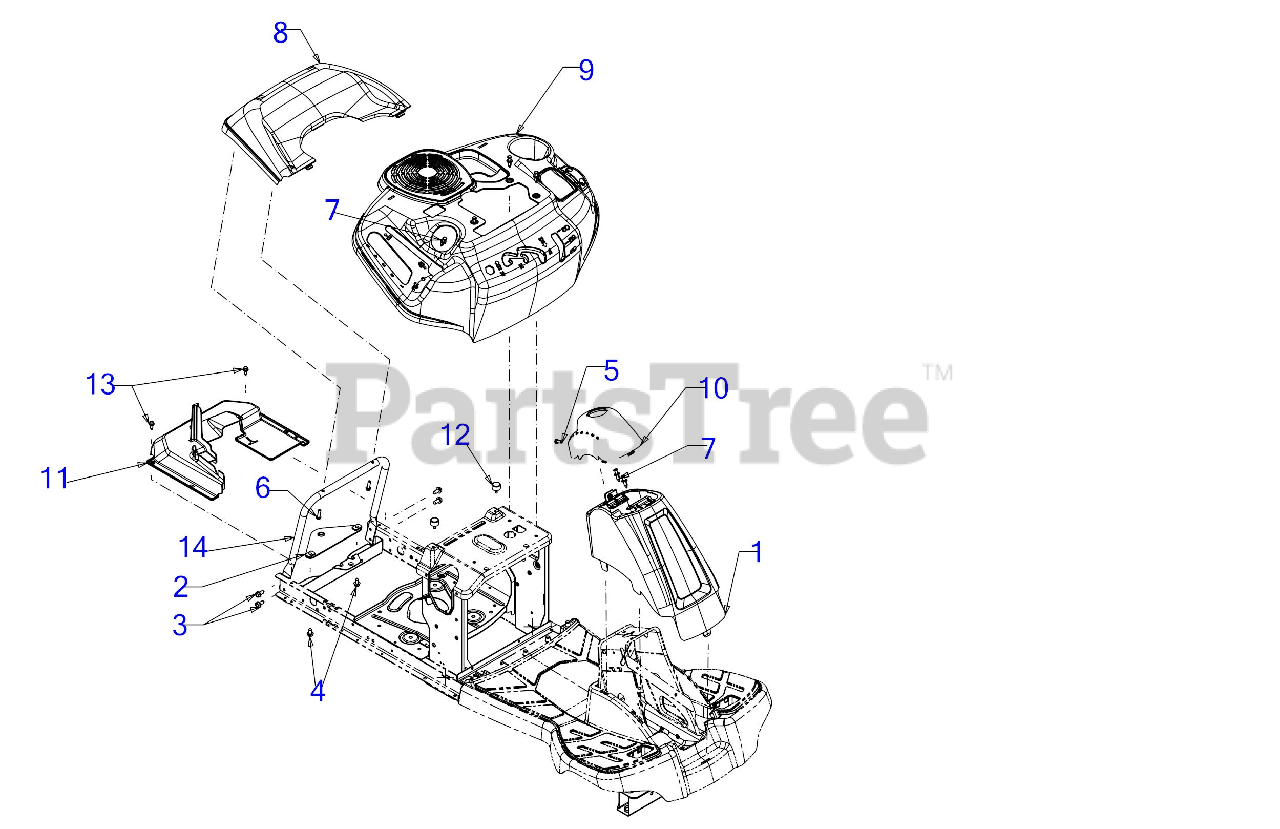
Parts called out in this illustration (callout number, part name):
1	COLUMN COVER ASSEMBLY (MTD RED)
3	SCREW 5/16-18 x .750
4	SCREW 5/16-18 x .625
5	SCREW 1/4-20X.75
6	SCREW 1/4-15 x 1.00
7	PLASTIC RIVET
9	FENDER
10	COLUMN STEERING CAP
11	DRIVE OVER REAR
12	BUMPER .62 DIA x .50
13	SHOULDER SCREW
